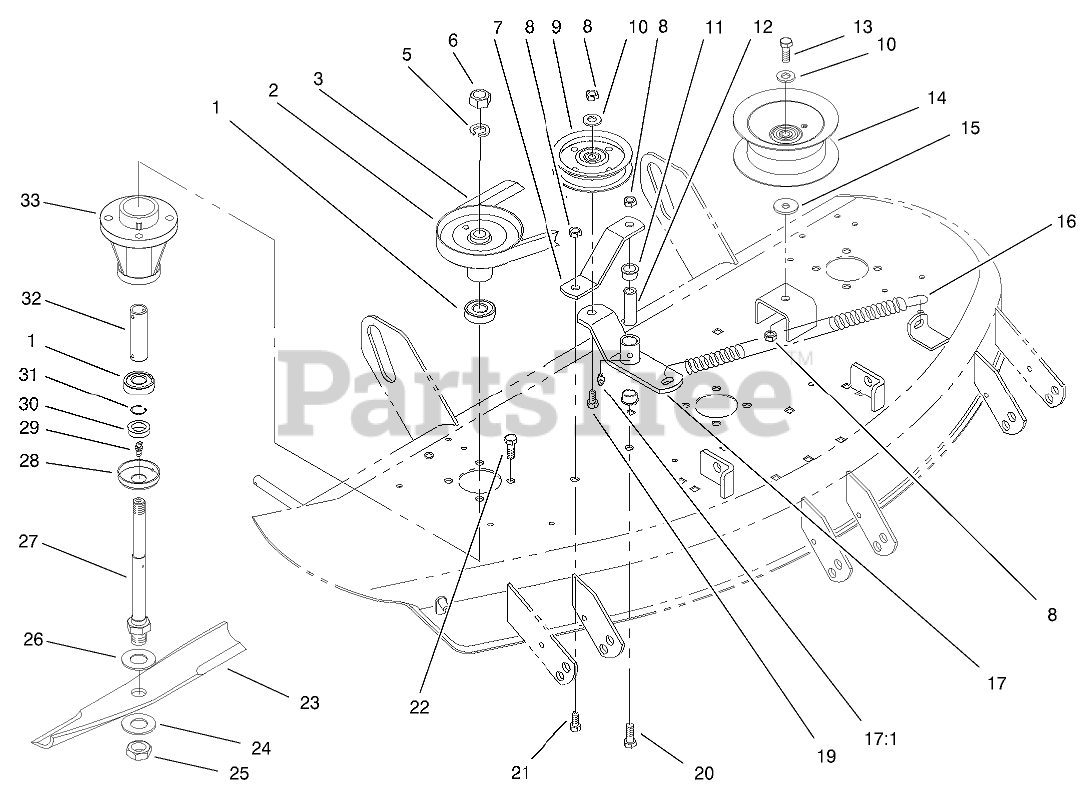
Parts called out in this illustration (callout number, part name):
1	BEARING-BALL
2	PULLEY
3	V-BELT
5	WASHER-LOCK
6	NUT-JAM
7	STRAP-BRACE
8	NUT-LOCK, NI
9	PULLEY-IDLER, FLAT
10	WASHER-FLAT
11	BUSHING
12	SPACER
13	SCREW-HH
14	PULLEY-IDLER
15	WASHER
16	SPRING - EXTENSION
17	ARM - IDLER
17:1	FITTING-GREASE
19	SCREW-HH
20	SCREW-HH
21	SCREW-HH
22	SCREW-HH
23	14IN BLADE KIT
24	WASHER-FLAT
25	NUT-JAM
26	WASHER-FLAT
27	SHAFT-SPINDLE
28	CUP-SPINDLE
29	FITTING-GREASE
30	SPACER-BLADE
31	RING-RETAINING
33	HOUSING-SPINDLE
